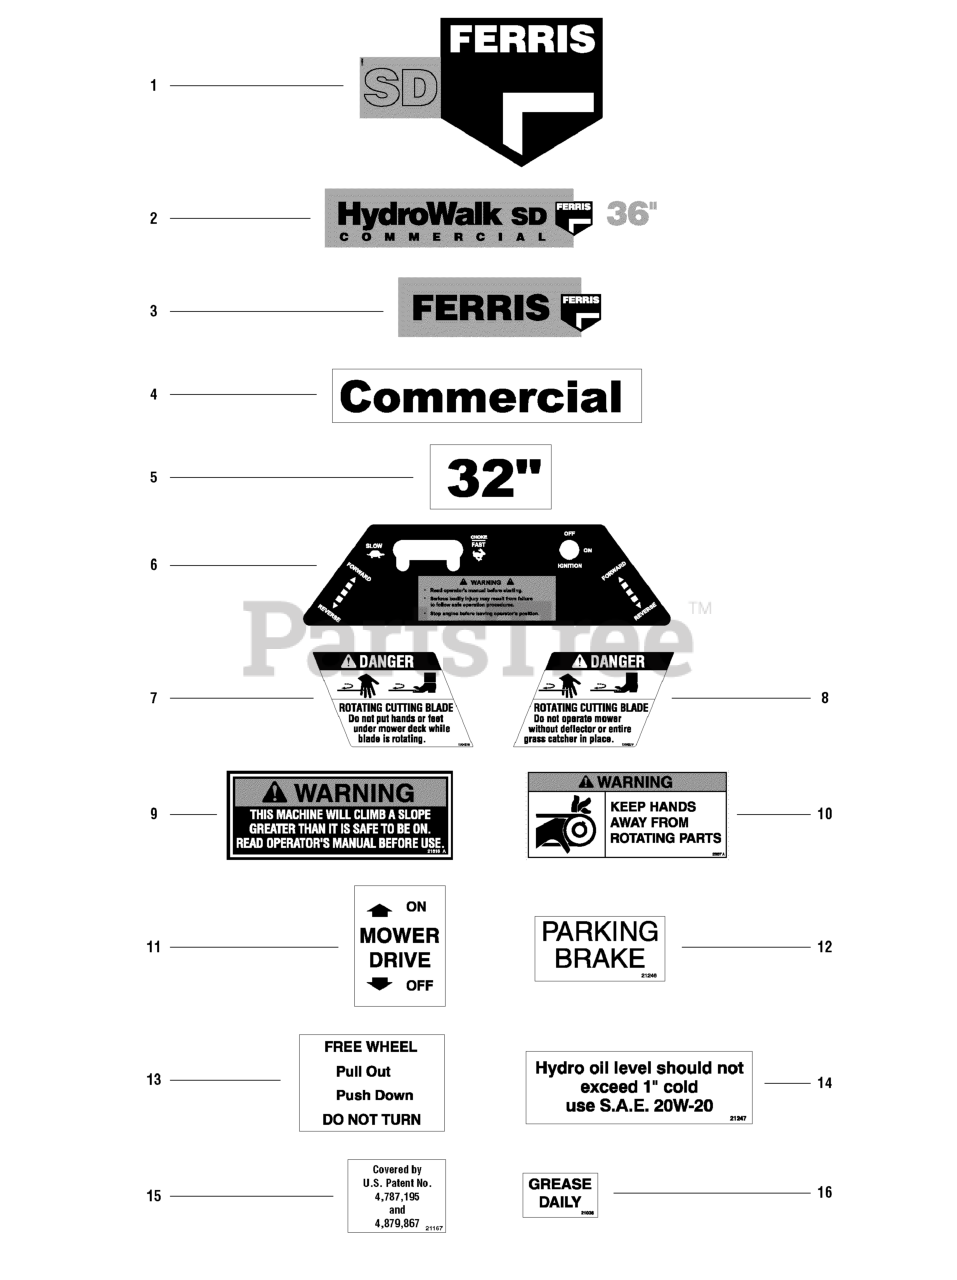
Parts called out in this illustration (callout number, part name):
1	DECAL, Ferris Logo, SD
2	DECAL, HydroWalk
3	DECAL, FERRIS TEXT & LOGO
4	DECAL, Commercial
5	DECAL, 32"
6	DECAL, HW Dash
7	DECAL, Danger (Hand Under Deck)
8	DECAL, Danger (Chute In Place)
9	DECAL, Warning, Machine Will Climb
10	DECAL, Warning
11	DECAL, Mower Drive On / Off
12	DECAL, Parking Brake
13	DECAL, Free Wheel
14	DECAL, Hydro Oil Level
15	DECAL, Walker Patent Number
16	DECAL, Grease Daily
